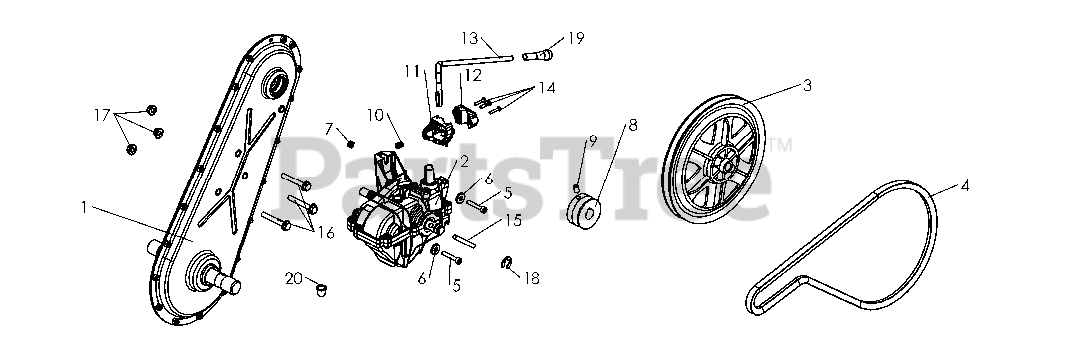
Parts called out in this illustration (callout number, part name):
3	PULLEY
5	BOLT
6	WASHER
7	Blocking nut M 6 Z
8	PULLEY
9	SCREW
15	SHAFT
18	RETAINER RING
